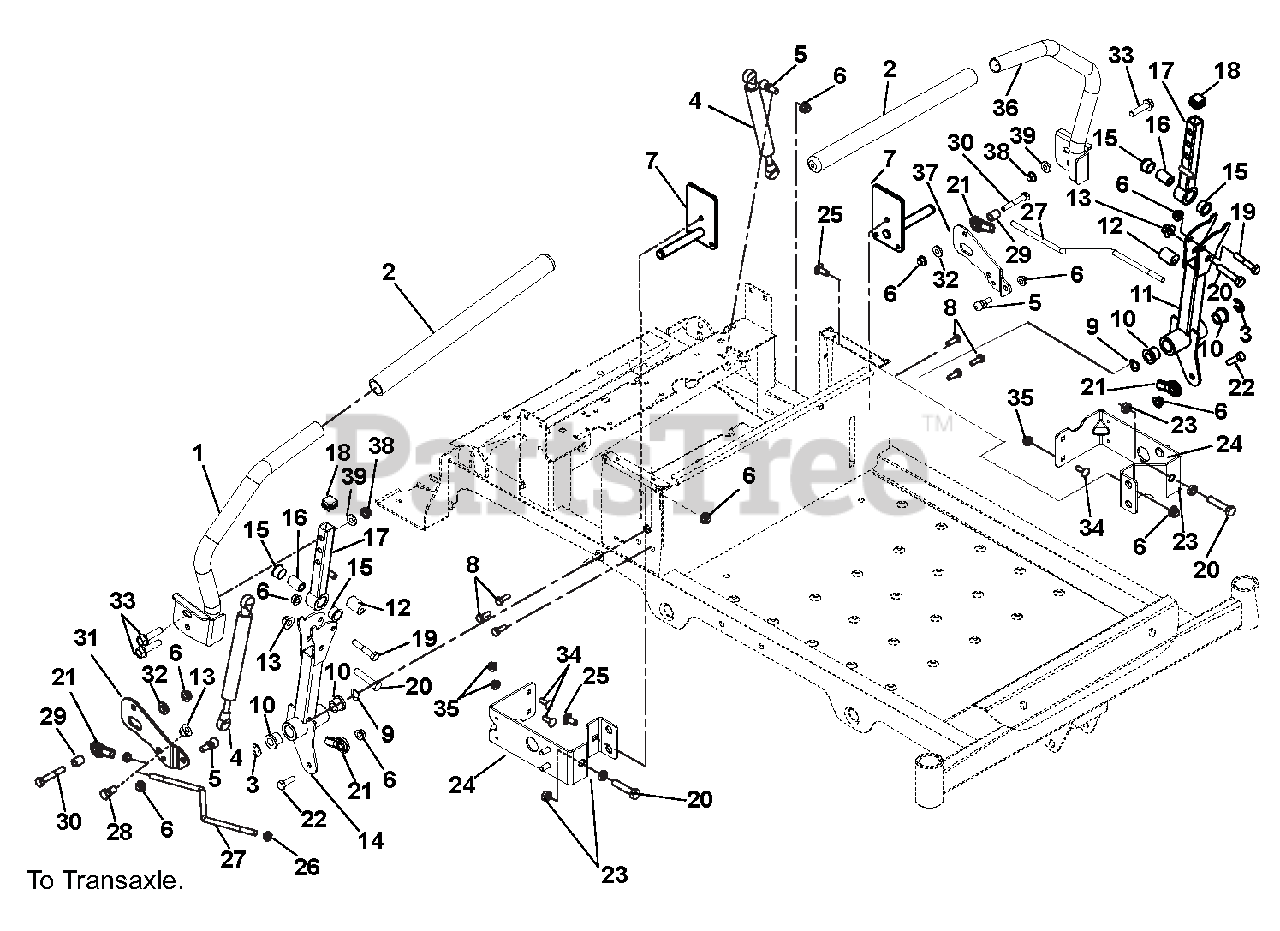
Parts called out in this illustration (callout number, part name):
1	WMT, STEERING HANDLE
2	GRIP, HANDLEBAR 15" FOAM
3	RG-RTNG-EXT .500X.042 (E)
4	DAMPER, STABILUS
5	STUD- BALL
6	@NUT-LK-NYL-FLG .31-18 YWZC
7	WMT, STEERING SHAFT
8	SCR-TAP .25-20X.50 HWH TR YWZ
9	WSHR-WAVE .50X.75X.015 .13FRHT
10	BSHG-FLG .500X.750X.625X.937
11	WMT, LOWER CONTROL ARM
12	BSHG, ECCENTRIC .328X.750X.970
13	@NUT-LK-NYL-FLG .38-16 YWZC
14	WMT, LOWER CONTROL RH
15	BSHG-FLG, .625X.75X.450X.875
16	SPACER, .375X.625X.970 (PM)
17	WMT, UPPER CONTROL ARM
18	CAP PLUG, SQ 3/4-14-20 RIBBED
19	@BLT-HEX .31-18X1.75 GR5 YWZC
20	BLT-HEX .375-16X1.750 FTD YWZC
21	ALIGNABALL, 5/16 RH THREAD
22	@BLT-HEX .31-18X1.00 GR5 YWZC
23	NUT-HEX-JAM .375-16 YWZC
24	WMT, STEERING STOP
25	@BLT-RHDSSQNK .31-18X.75 G5YZ
26	NUT-JAM .31-24 YWZC
27	WIREFORM, STEERING LINK
28	@BLT-HEX .38-16X.75 GR5 YWZC
29	SPACER, .328X.500X.625
30	@BLT-HEX .31-18X2.00 GR5 YWZC
31	PLATE, DAMPER RH
32	BSHG-FLG .316X.430X.225X.750
33	BLT-SERHFWH .375-16X1.25 YWZC
34	@BLT-RDHDSQNK .25-20X.75 G5YZ
35	@NUT-LK-NYL-FLG .25-20 YWZC
36	WMT, STEERING HANDLE LH
37	PLATE, DAMPER (LH)
38	@NUT-LK-CTR-JAM .375-16 YWZC
39	@WSHR-FL-STL.406X.812X.065 YWZ
